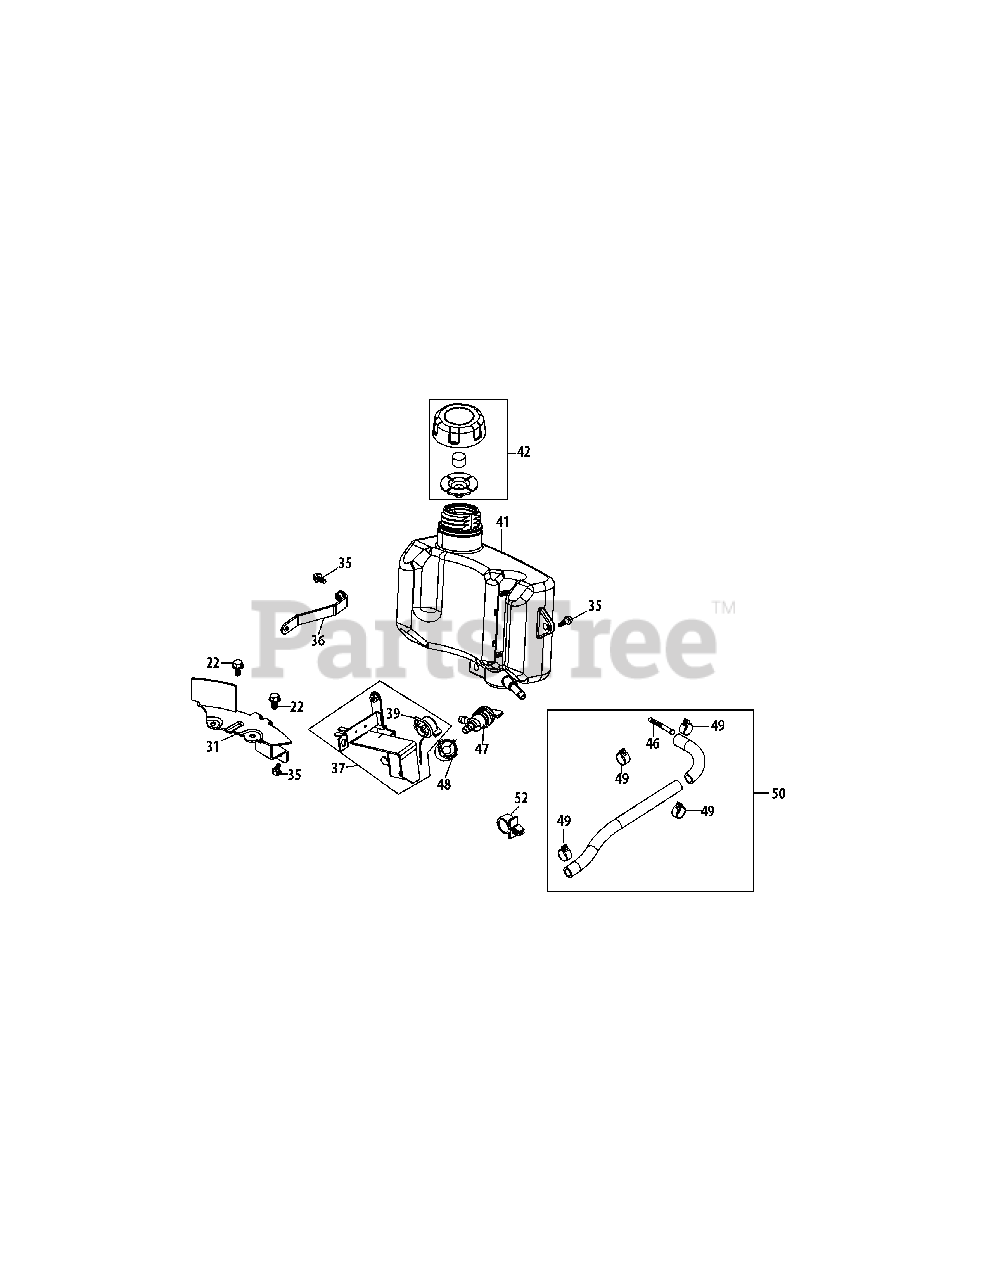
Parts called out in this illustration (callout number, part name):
22	Bolt M6X14 Multi-Purpose
31	Fuel Tank Bottom Bracket
35	Fuel Tank Bolt (Carb)
36	Left Fuel Tank Bracket
37	Fuel Tank / Console Bracket Assy
39	Ignition Switch
41	Fuel Tank
42	Fuel Cap Assembly
46	Fuel Filter
47	Fuel Shut-Off Valve
48	Fuel Shut-Off Valve Mounting Clip
49	Fuel Hose Clamp
50	Fuel Line Kit
52	Plastic Support Clamp
